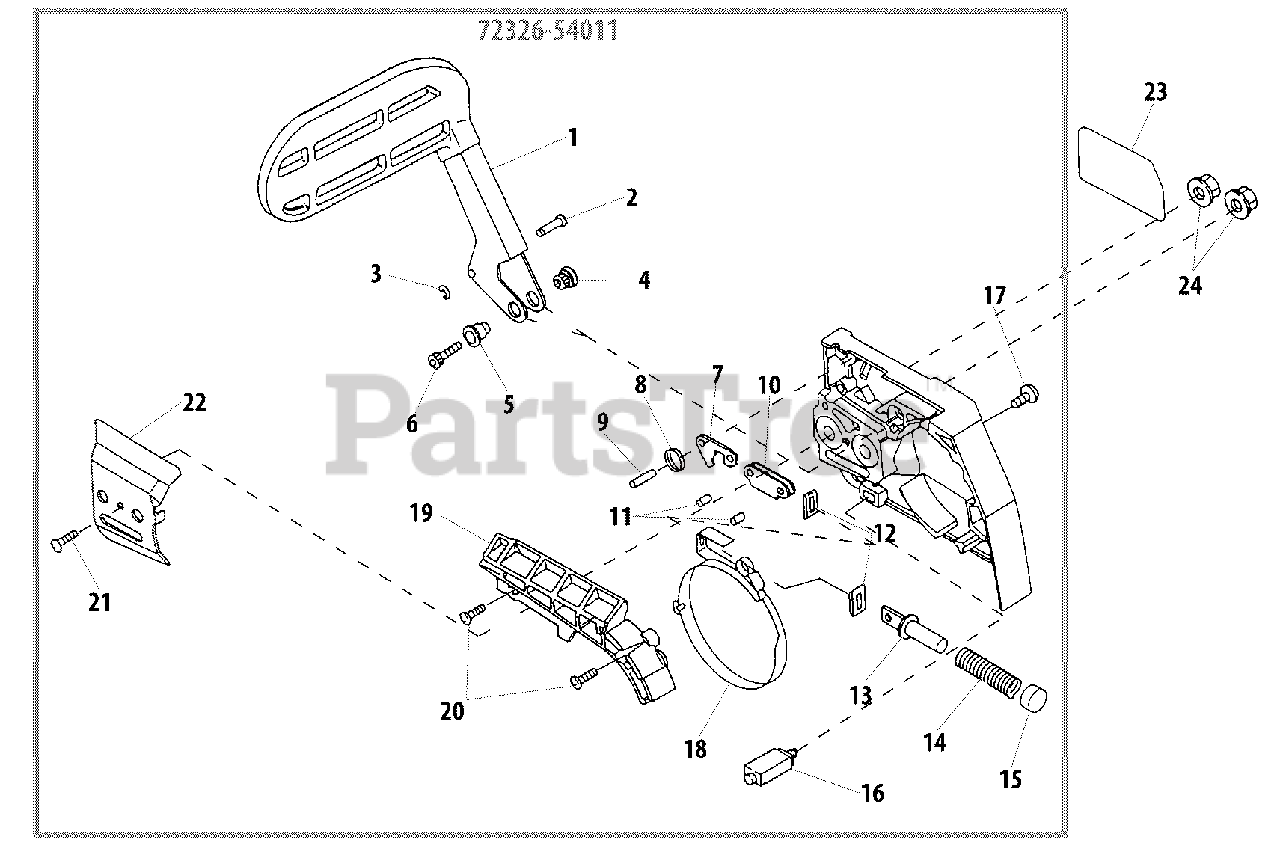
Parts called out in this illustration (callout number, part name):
1	LEVER
2	PIN, LEVER
3	RING, SNAP 3 MM
4	NUT
5	HOLDER
6	BOLT 4×12
7	LEVER, INNER
8	SPRING, LEVER
9	PIN, LOCATING
10	STRAP, TIE
11	PIN, LOCATING Ø4×8
12	PLATE, ADJUST
13	HOLDER, SPRING
14	SPRING, BRAKE
15	STOPPER
16	CHAIN CATCHER
17	SCREW, TRUSS 3×10
18	BAND, BRAKE
19	COVER
20	SCREW, TAPPING 4×12
21	SCREW, TAPPING 4×8
22	PLATE, GUIDE B
23	LABEL - MODEL
24	NUT
72326-54011	BRAKE ASSY
